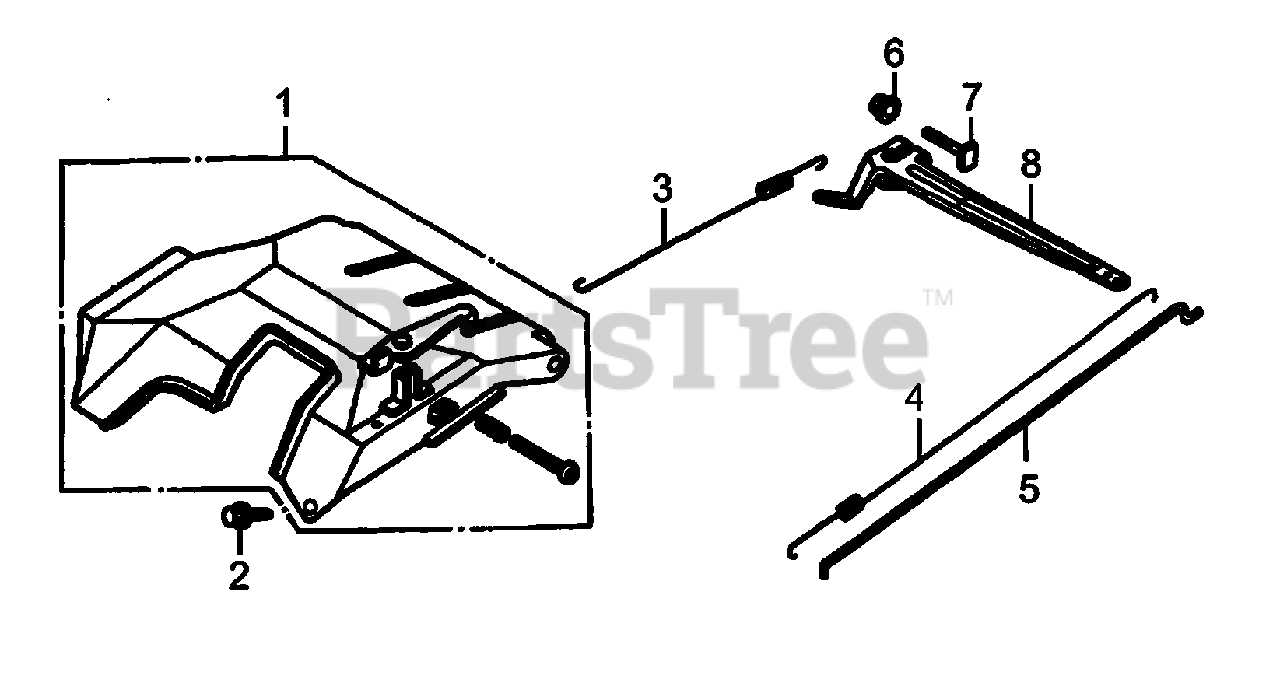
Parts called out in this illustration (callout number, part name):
1	CONTROL ASSY.
2	BOLT, FLANGE, 6X12
3	SPRING, GOVERNOR A
4	SPRING, GOVERNOR B
5	ROD, GOVERNOR
6	NUT, FLANGE, M6
7	BOLT, GOVERNOR ARM
8	ARM, GOVERNOR
